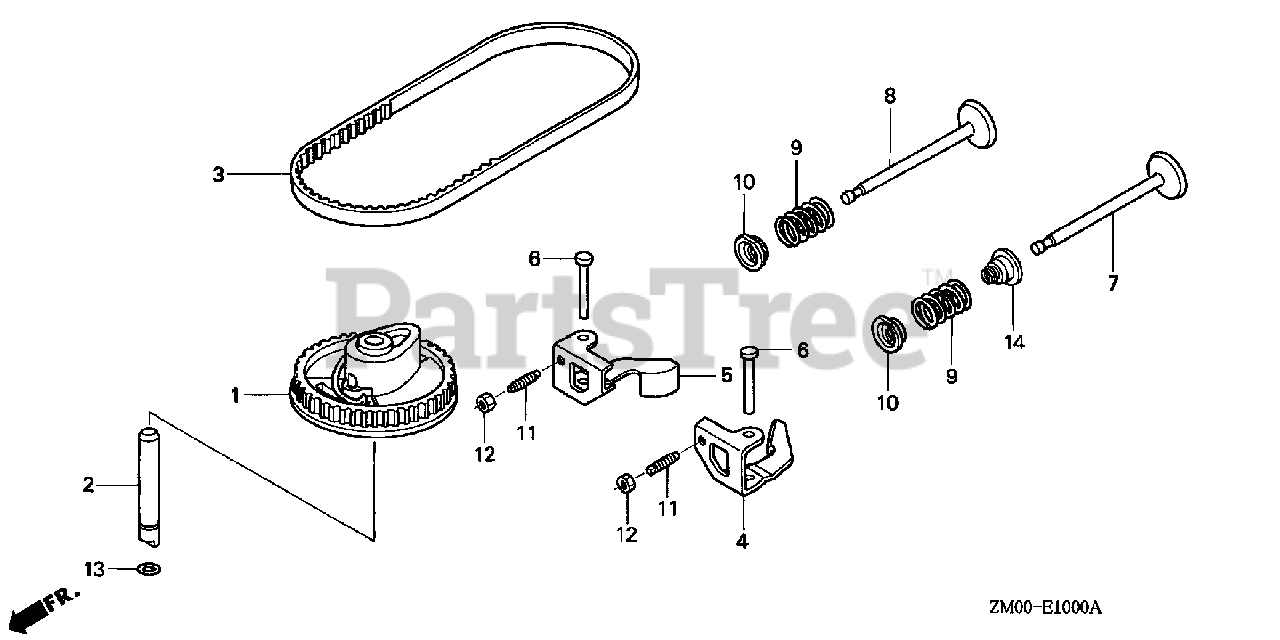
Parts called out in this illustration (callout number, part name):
1	PULLEY, CAMSHAFT
2	SHAFT, CAM PULLEY
3	BELT, TIMING (79HU7 G-200)
4	ARM, IN. VALVE ROCKER
5	ARM, EX. VALVE ROCKER
6	SHAFT, ROCKER ARM
7	VALVE, IN.
8	VALVE, EX.
9	SPRING, VALVE
10	RETAINER, IN. VALVE SPRING
11	SCREW, TAPPET ADJ.
12	NUT, TAPPET ADJ.
13	O-RING (6.8X1.9)
14	SEAL, VALVE STEM
